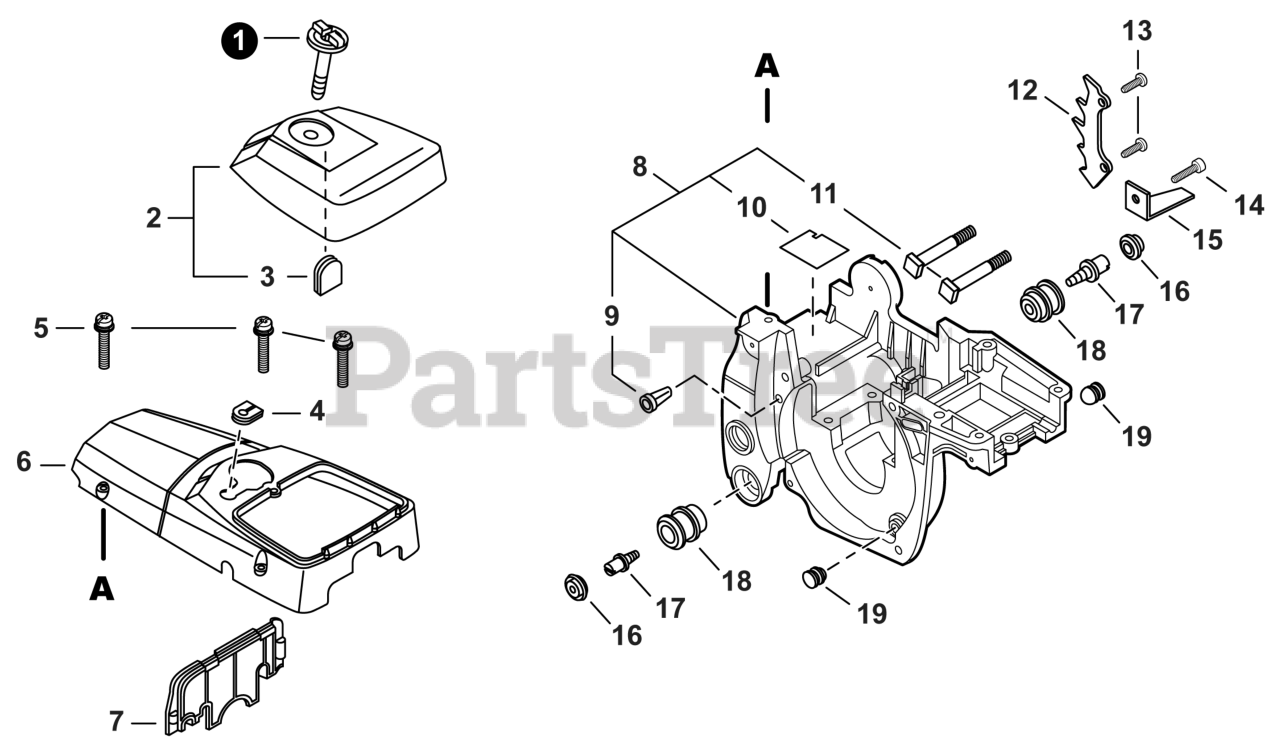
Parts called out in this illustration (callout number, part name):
1	THUMBSCREW
2	COVER ASSY, AIR FILTER
4	GROMMET
5	SCREW 5×20
6	COVER, ENGINE
7	PLATE, INSULATOR
8	COVER ASSY, ENGINE
9	CHECK VALVE
10	SHIELD, HEAT
11	STUD, GUIDE BAR 8
12	SPIKE, BUMPER
13	BOLT 5×16
14	BOLT 5×16
15	CHAIN CATCHER
16	CAP, CUSHION
18	CUSHION 5
19	CUSHION
